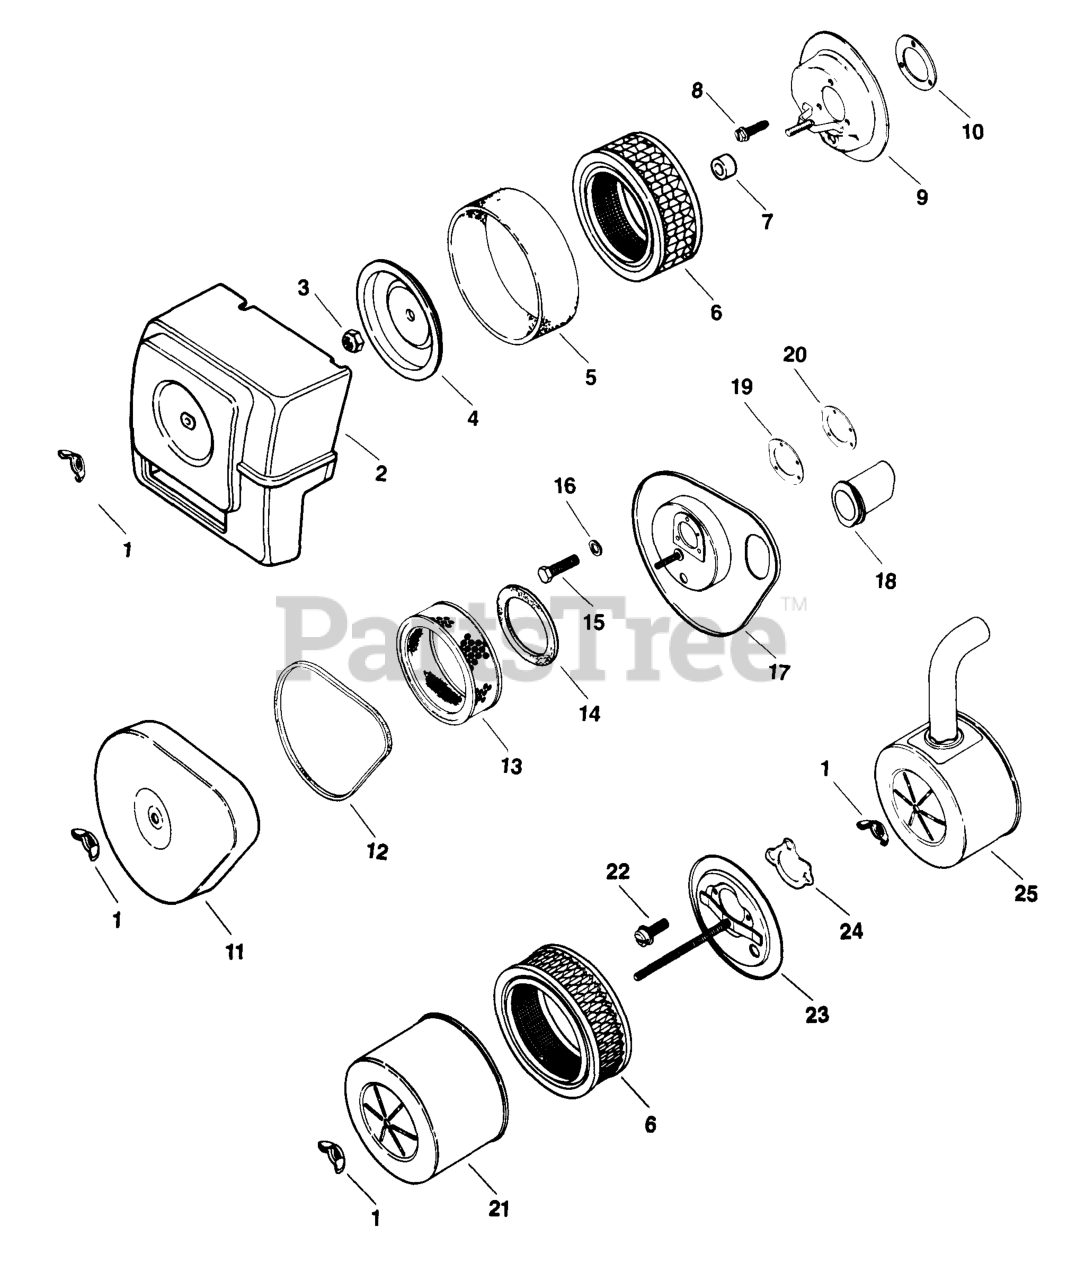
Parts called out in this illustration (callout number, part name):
1	NUT, WING 1/4-20 USE 25 100 15-S
12	SEAL-(#DSC)
15	SCREW, WSH HD TAP #10-32X15/16"
16	WASHER
17	BASE - DISCONTINUED
19	GASKET - USE 45 041 07
20	SPACER-DISCONTINUED
4111302-S	DECAL, AIR CLEANER INSTRUCT
